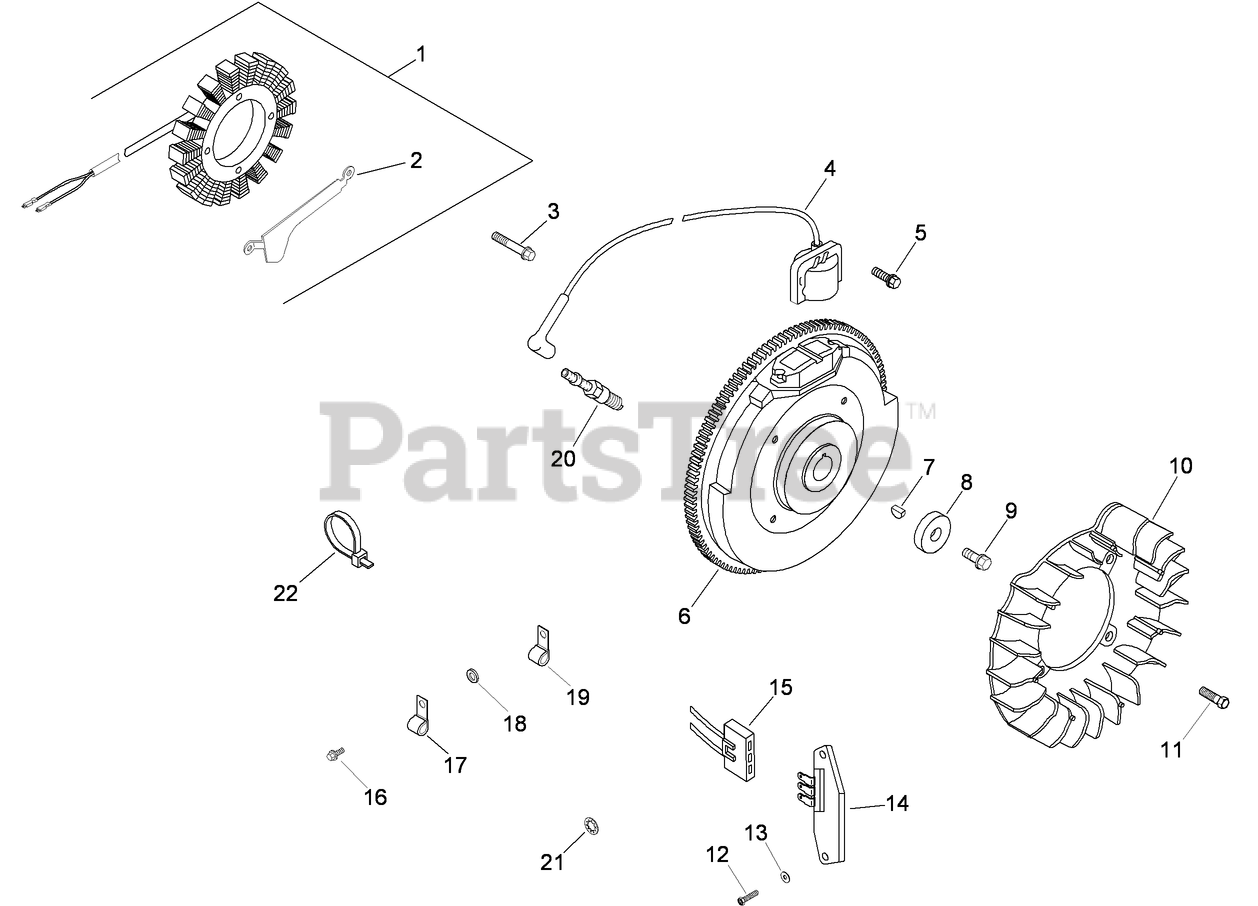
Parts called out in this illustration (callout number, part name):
1	15 Amp Stator Kit (Includes Ref 2)
2	Bracket-Wire, Stator
3	SCREW-THREAD FORMING (M5X0.8X25)
4	Module-Ignition
5	SCREW-FLANGE, THREAD FORMING (M5X.8X20)
6	Flywheel
7	KEY (3/16 X 5/8)
8	WASHER-FLAT (13/32)
9	SCREW-FLANGE (M10X1.5X45)
10	Fan
11	BOLT-SHOULDER (M6x1.0x16)
12	SCREW-PHL HD (11-16X.88)
13	WASHER-FLAT (.188)
14	Rectifier-Regulator, 15 amp
15	Connector (3 contact)
16	Screw-WSH HD Tap (8-18X.50)
17	CLIP-CABLE (B+ lead)
18	WASHER-FLAT (1/4)
19	Clip-Cable (clamps wires to intake manifold)
20	Spark Plug
21	Washer-Lock, Internal Tooth (1/4)
22	TIE-WIRE
